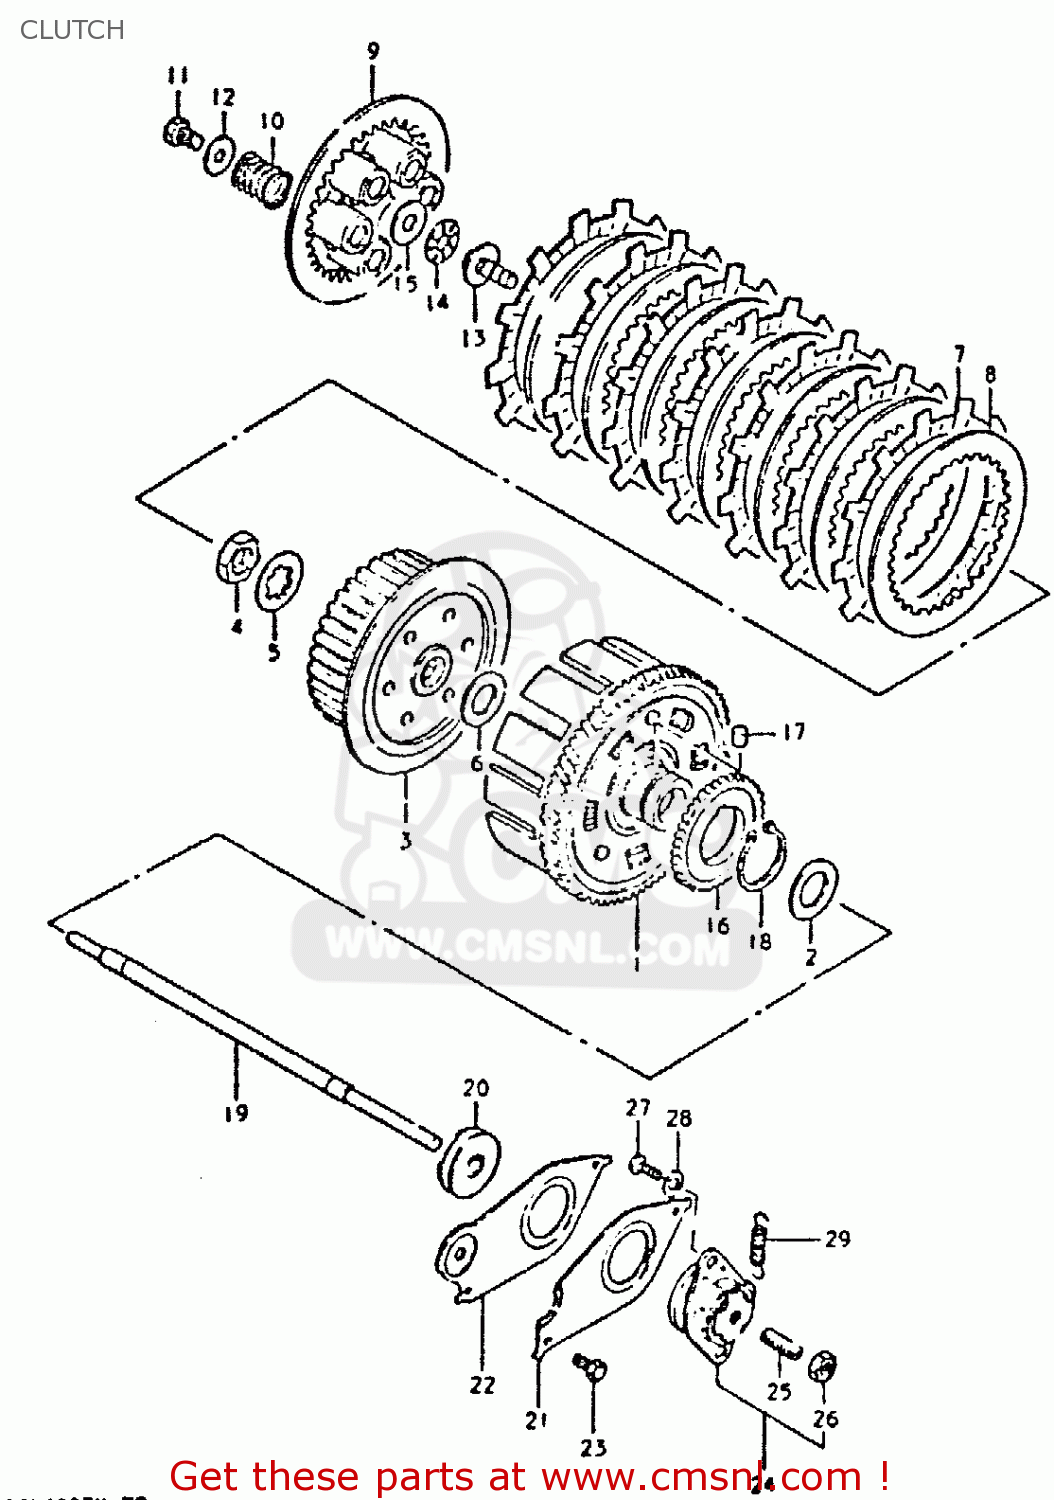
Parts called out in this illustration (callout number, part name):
1	GEAR ASSEMBLY,PRIMARY DRIVE
2	WASHER
3	HUB,CLUTCH SLEEVE
4	NUT (20MM)
5	WASHER,LOCK
6	WASHER(20X44X3)
7	PLATE,CLUTCH DRIVE (MCA)
8	PLATE,CLUTCH DRIVEN (NAS)
9	DISC,CLUTCH PRESSURE
10	SPRING
11	BOLT, UPPER
12	WASHER
13	PIECE,CLUTCH PUSH
14	BEARING(15X28X2)
15	WASHER
16	GEAR,OIL PUMP DRIVE
17	PIN(6X6)
18	CIRCLIP
19	ROD,CLUTCH PUSH
20	SEAL,OIL(6X34X8)
21	PLATE,CLUTCH PUSH ROD
22	PLATE,CLUTCH PUSH ROD
23	BOLT
24	SCREW ASSEMBLY,CLUTCH RELEASE
25	SCREW
26	NUT 6MM
27	SCREW
28	WASHER
29	SPRING
